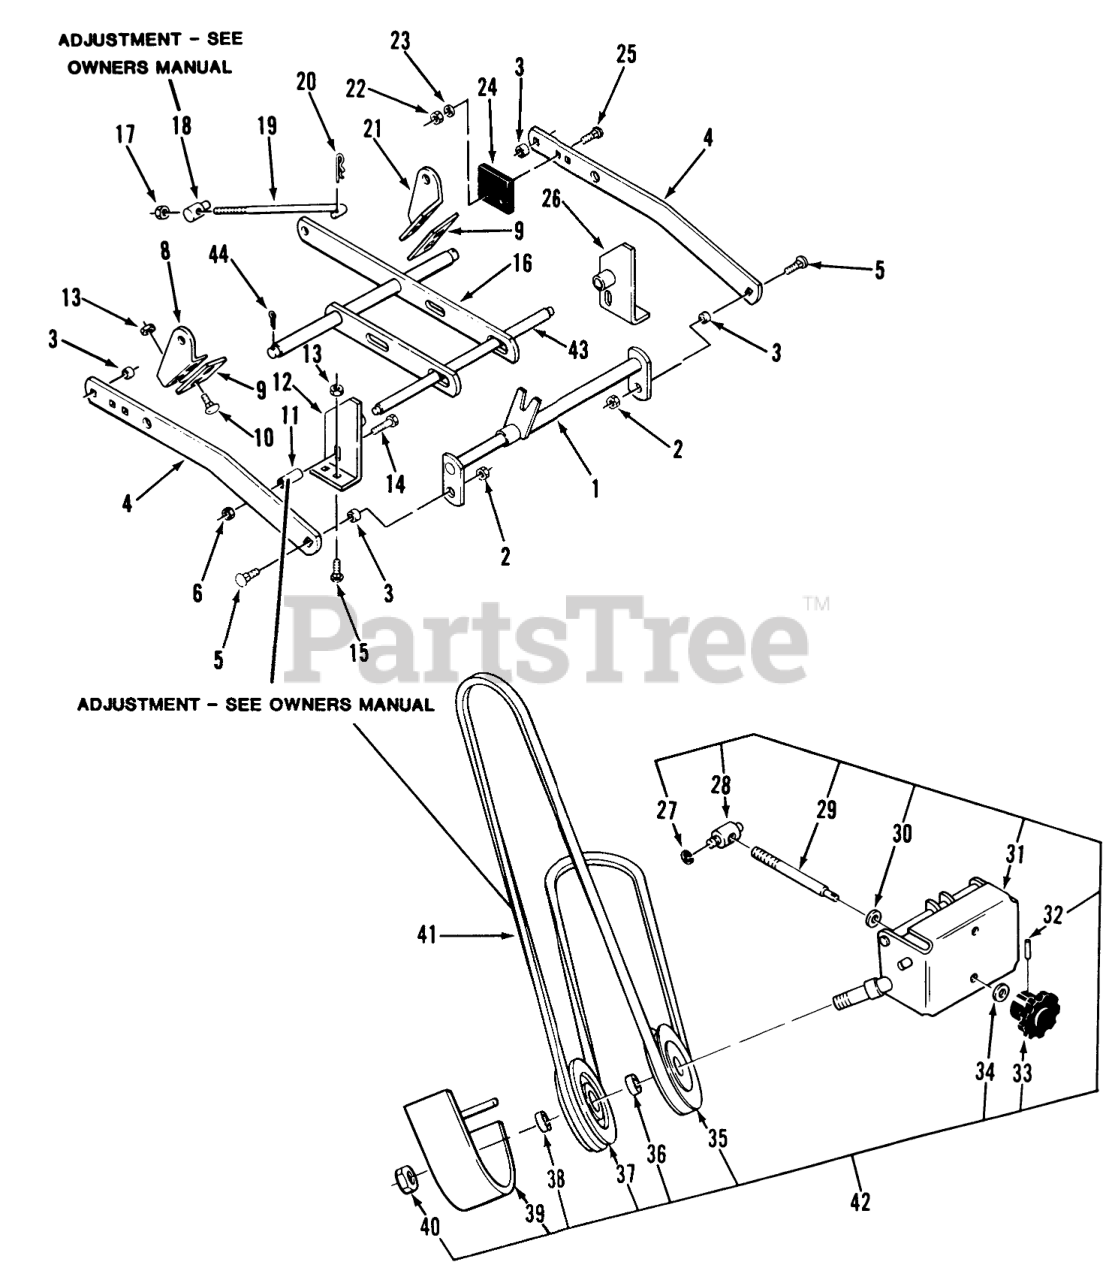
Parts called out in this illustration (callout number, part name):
1	Hitch
2	LOCKNUT-FLANGE
3	SPACER
4	Bar Draft
5	Bolt
6	Nut
8	Bracket-Rt. Rear
8	Bracket-R.H.
9	PLATE
9	Plate
10	Bolt
12	Bracket-R.H.
13	Nut
14	CARRIAGE BOLT -4
15	Bolt-Carriage
16	Leveler
17	NUT
18	TRUNNION-LIFT
19	Lift Rod
19	ROD-LEVELER
20	Hairpin
21	Bracket-L.H. Rear
21	Bracket-L.H.
22	Nut
23	Collar
24	BUMPER
25	Bolt-Carriage
26	Bracket-L.H.
27	RING-RETAINING
28	TRUNNION-DOUBLE
29	ROD ADJ
30	Washer
31	Front Support
31	ASSY FRONT SUPT
32	PIN-ROLL
33	KNOB-ADJUSTMENT
34	WASHER-SPRING
35	Pulley-V
36	SPACER
37	PULLEY-FLAT IDLER
38	SPACER-OUTER
39	Belt Cover
39	ASSY BELT COVER
40	Nut
40	Chrome Eslok Nut 3/4-16 (used with 420-LSE)
41	V-BELT
42	ASM-SUPPORT,IDLER
42	Chrome Front Idler Assy (used with 420-LSE)
43	Front Shaft
44	Cotter Pin
